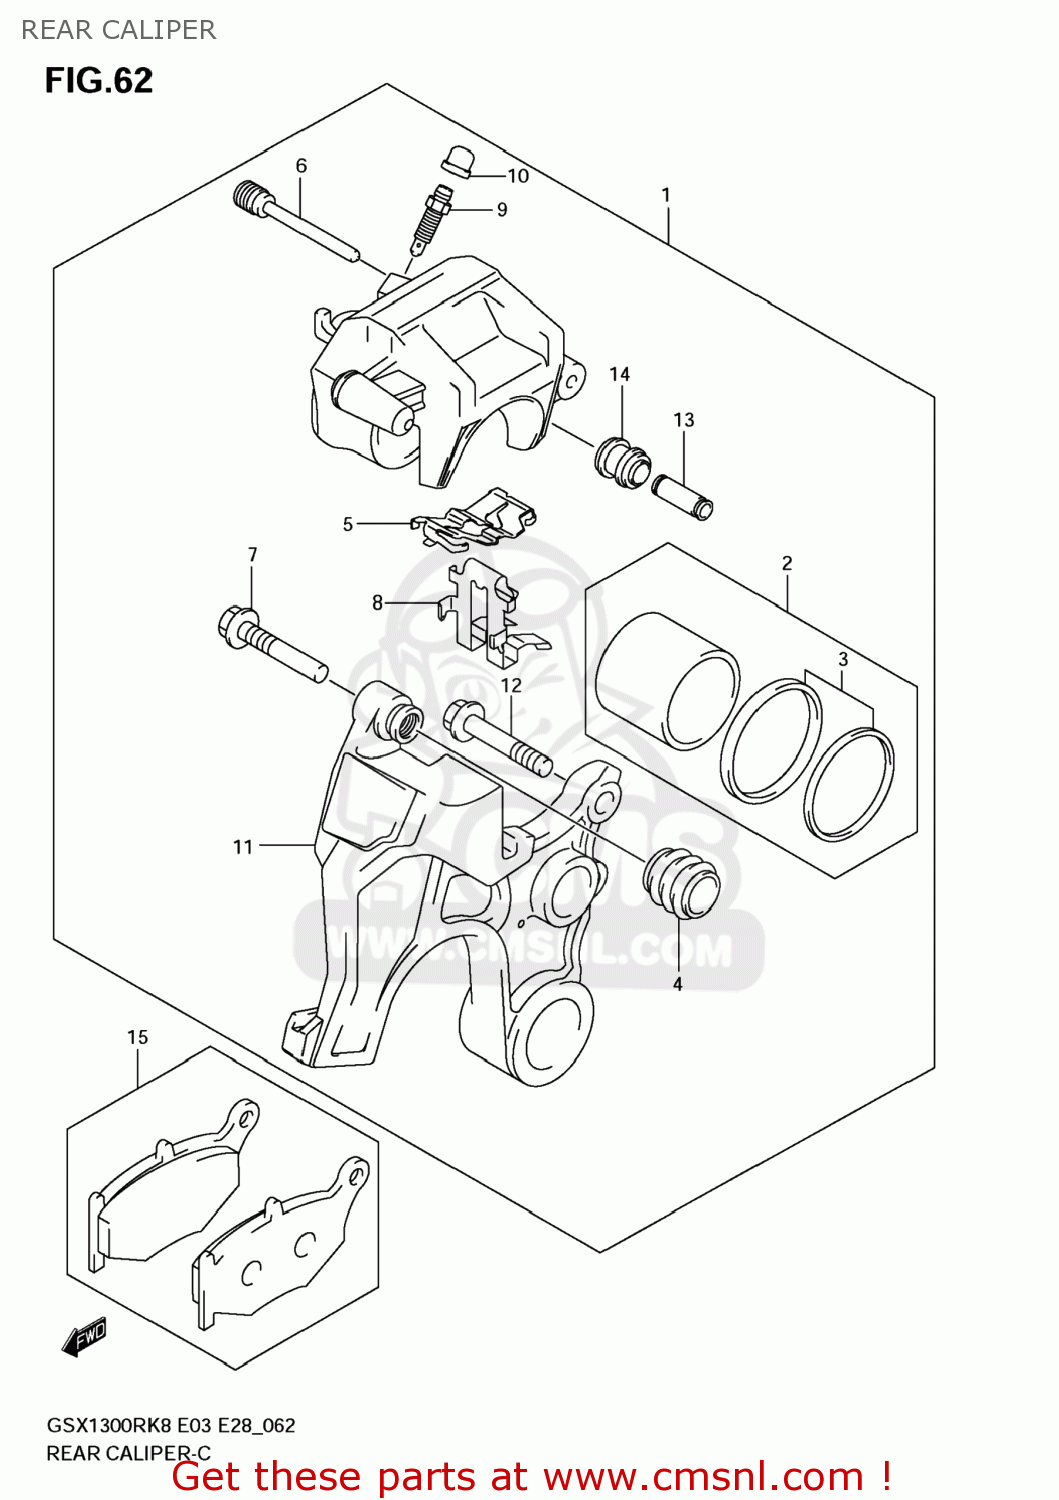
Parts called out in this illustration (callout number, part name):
1	CALIPER ASSY,RR
2	PISTON SET
3	SEAL SET,PISTON
4	BOOT,AXLE
5	SPRING,PAD
6	PIN,PAD
7	PIN,BOLT
8	RETAINER
9	BLEEDER
10	CAP,BLEEDER PLUG
11	BRACKET
12	BOLT
13	SLEEVE
14	BOOT,SLEEVE
15	PAD SET (NAS)
